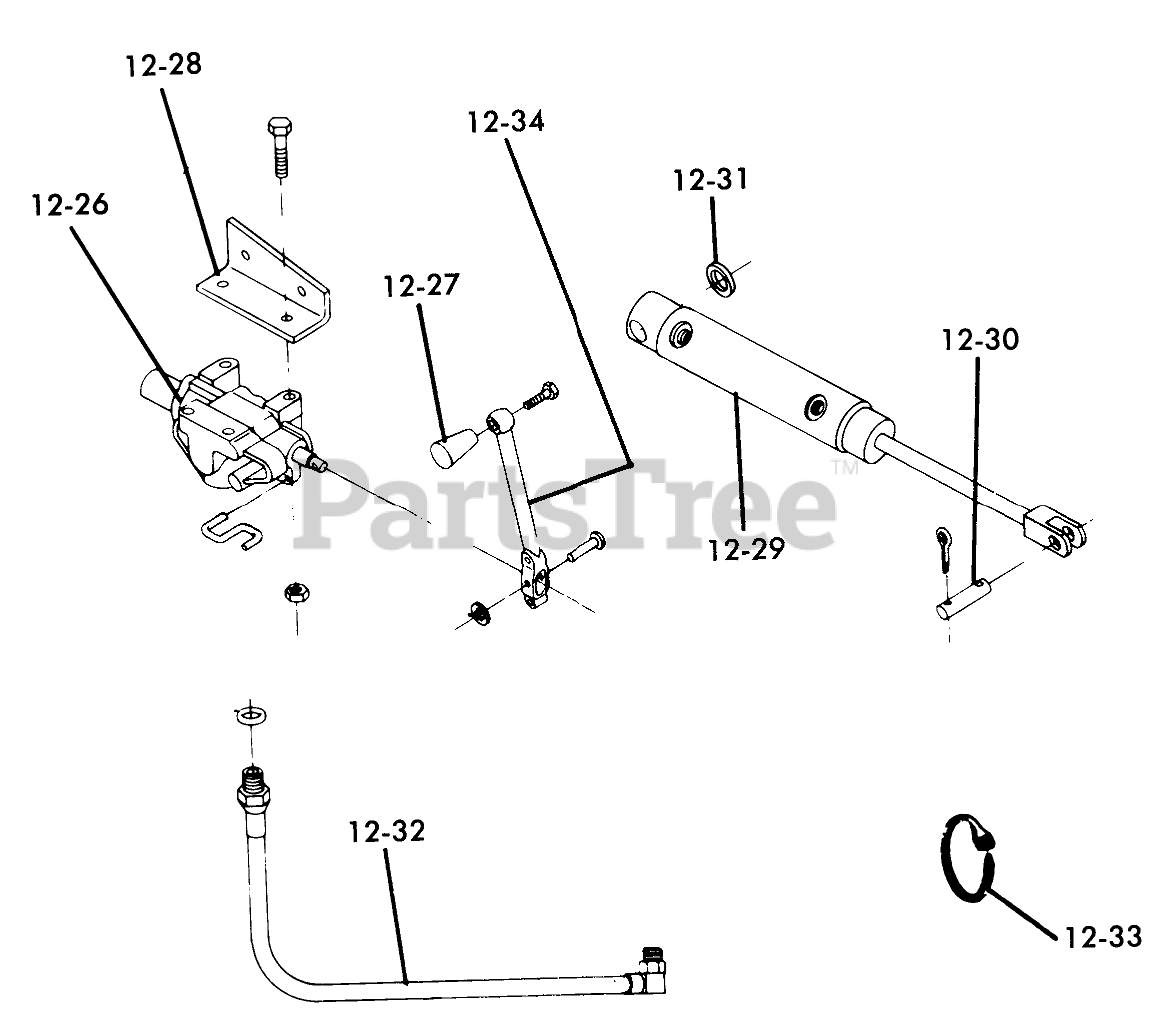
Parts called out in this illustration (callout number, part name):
12-26	Valve
12-26	Ring Kit
12-26	Spool Cap Kit
12-27	KNOB
12-27	SCREW
12-28	SUPPORT-VALVE
12-28	Bolt
12-28	Bolt 1/4-20 X 1 1/2
12-28	Nut
12-29	Cylinder
12-30	PIN
12-31	Spacer
12-32	16" Hose Assembly
12-32	HOSE HYDRAULIC 19"
12-32	ASSY-HYDRAULIC HOSE
12-32	HYD HOSE ASSY
12-33	PLASTIC TIE
12-34	Assy-Handle
